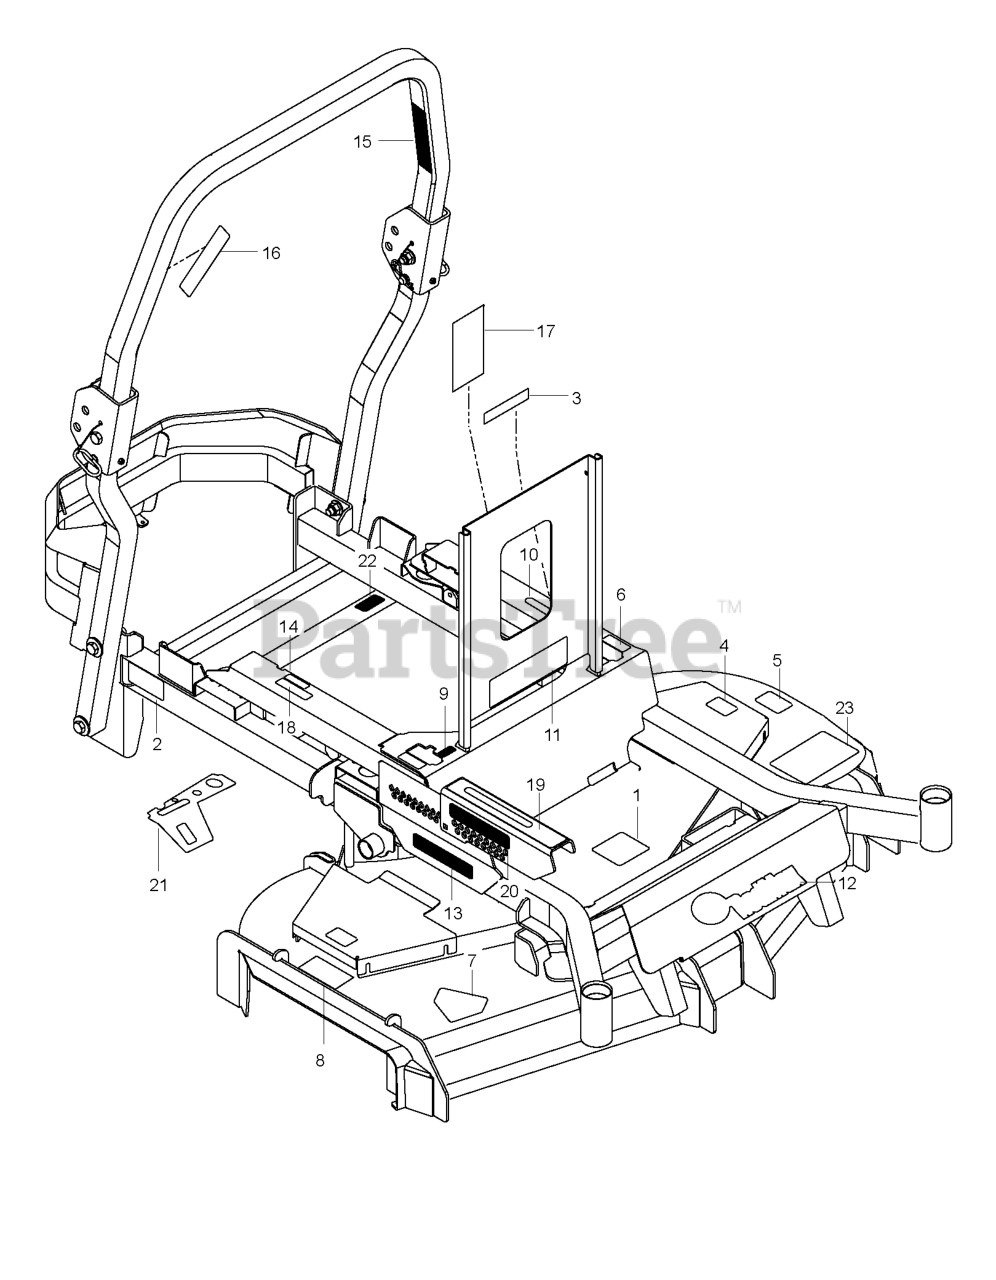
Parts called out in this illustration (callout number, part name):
1	DECAL, BELT ROUTING
2	DECAL, BELT DRIVE
3	EURO DECAL-BATTERY WARNIN6
4	DECAL.DECK.6MIL.EURO.NOSTEP
5	DECAL DECK DECAL DECAL.DECK.48
6	DECAL.ZTR.MTNCONTROL.2015.PPRO
7	DECAL, DECK DEFLECTOR, WARNING
8	DECAL.DECK.6MIL./DEF.SHLD.WARN
9	DECAL.ZTR.TRACKING.GRAPHIC
10	DECAL.ZTR.TRACKING.GRAPHIC
11	DECAL ZTR WARNING DECAL DECAL.
12	DECAL ZTR BRAND GRAPHIC DECAL.
13	DECAL ZTR SIDE RAIL GRAPHIC DE
14	DECAL ZTR INSTRUCTION GRAPHIC
15	DECAL, ROPS
16	DECAL, ROPS, WARNING
17	DECAL, SERVICE
18	DECAL, WARNING SPARK ARRESTOR
19	DECAL ZTR INSTRUCTION GRAPHIC
20	DECAL ZTR INSTRUCTION GRAPHIC
21	DECAL ZTR CONTROL PANEL DECAL.
22	DECAL ZTR INSTRUCTION GRAPHIC
23	FOOT PAD
